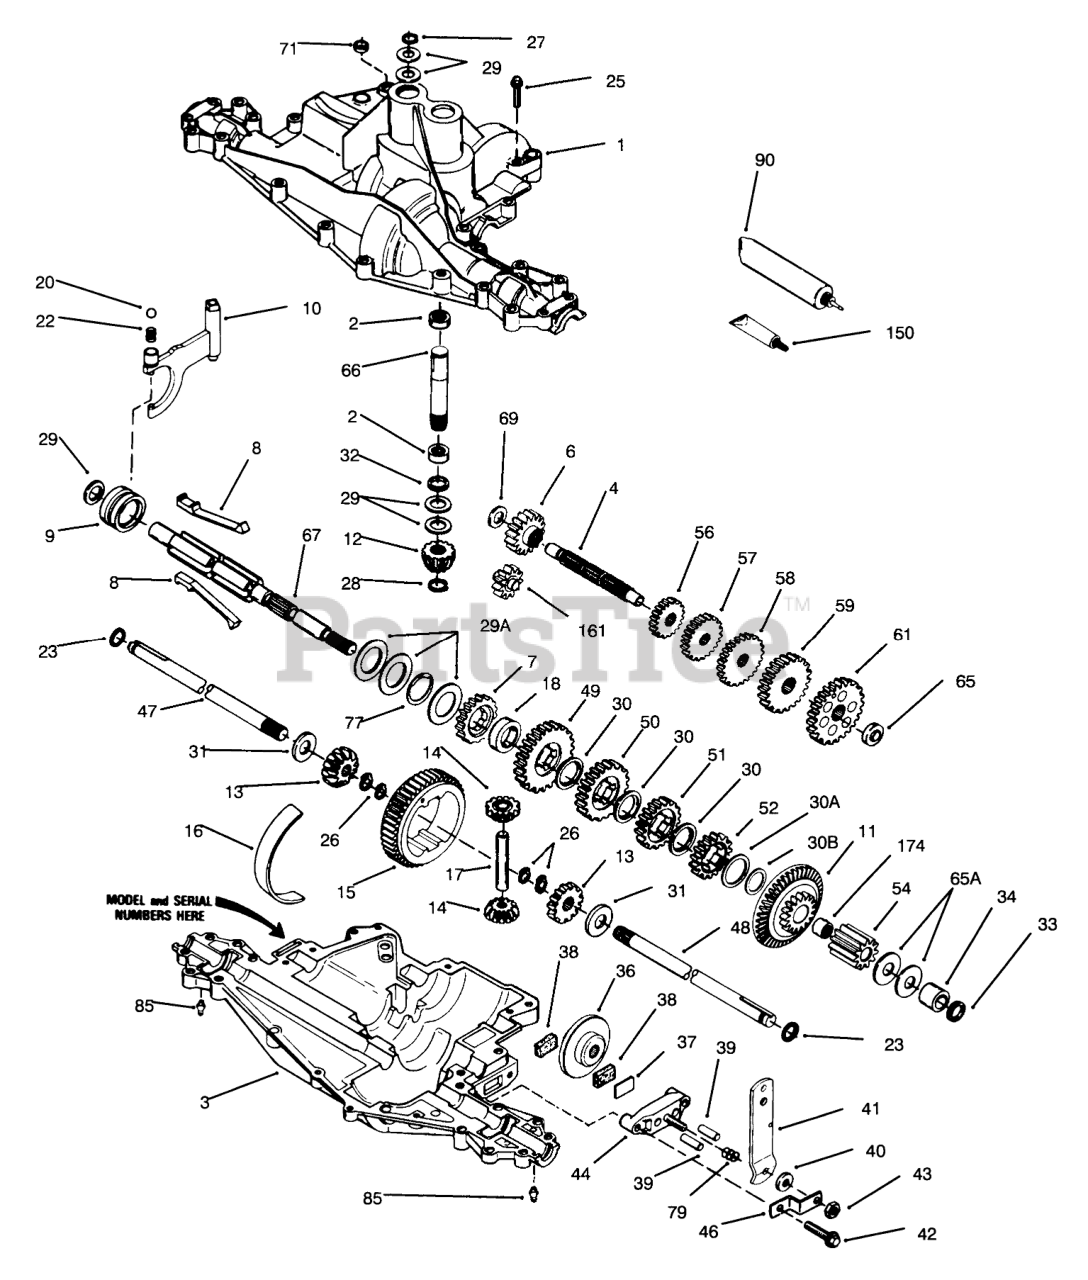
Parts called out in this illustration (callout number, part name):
1	Transaxle Cover
2	Bearing-Needle
3	Transaxle Case
4	Countershaft
6	Spur Gear (16 Teeth)
7	Gear-Spur (22 teeth)
8	Shift Key
9	Shift Collar
10	Shift Rod & Fork
11	Bevel Gear & Bearing (44/16 Teeth)(Incl. Ref. #174)
12	Bevel Pinion (14 Teeth)
13	Gear Bevel
14	Gear Pinion
15	Gear-Ring
16	Bearing Strip
17	Drive Pin
18	Neutral Spacer
20	Ball (3/8" dia.)
22	Spring
23	Ring-Seal
25	Ring Set (.020 O S)
26	Retaining Ring (pkg of 2)
27	Ring-Snap
28	Ring-Retainer
29	Washer
29A	Washer
30	Washer
30A	Washer
30B	Washer
31	Washer
32	O Ring
33	O-Ring
34	Bushing
36	Brake Disk
37	Brake Pad Plate
38	Brake Pad
39	Dowel Pin
40	Washer
41	Brake Lever
42	Ring Set (.020 O S)
43	Locknut
44	Nozzle-Carburetor
46	Bracket
47	Axle (16-3/4" Ig.)
48	Axle (11-9/16" Ig.)(Incl. Ref. #26)
49	Gear-Spur, 30 Teeth
50	Gear-Spur, 25 Teeth
51	Gear-Spur (22 teeth)
52	Gear Spur 19t
54	Spur Gear (11 Teeth)
56	Gear-Spur, 20 Teeth
57	Gear-Spur, 25 Teeth
58	Gear-Spur (28 teeth)
59	Gear-Spur (30 teeth)
61	Spur Gear (34Teeth)
65	Washer
65A	Washer
66	Input Shaft (3.522" Ig.)
67	Shifter & Brake Shaft
69	Thrust Washer
71	Cut Seal-Square
77	Inverted Retaining Ring
79	Piston ASM (.020 O S)
90	Grease 32 Oz
150	Gasket Eliminator
161	Reverse Idler Assembly
174	Needle Bearing
